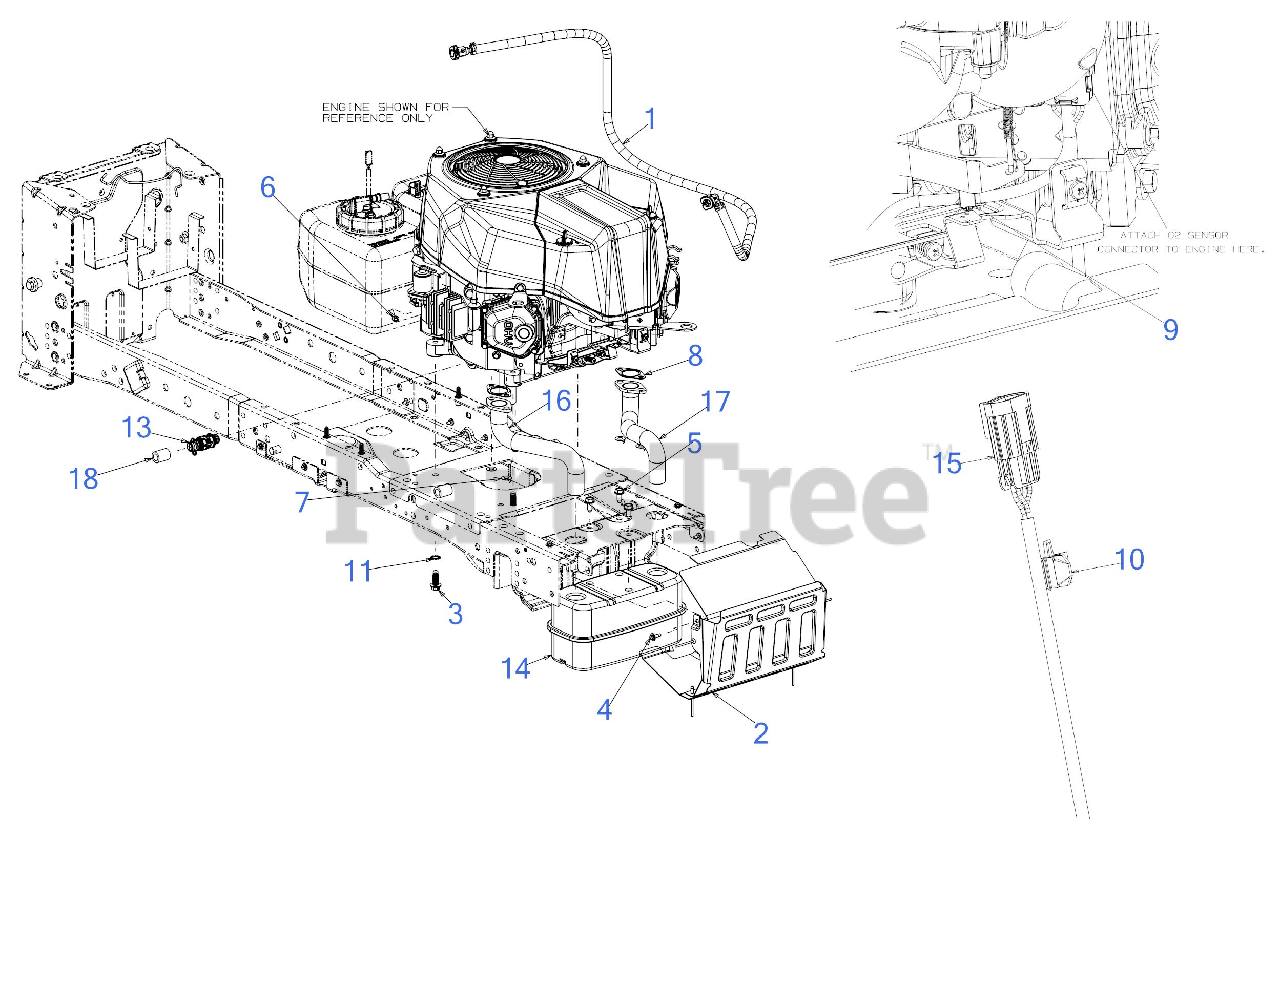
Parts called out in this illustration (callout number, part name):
1	HP FUEL HOSE ASSEMBLY
2	MUFFLER SHIELD ASSEMBLY
2	RIVET - 3/16"
3	SCREW 3/8-16 x 1
4	SCREW M6-1 x .625
5	SCREW M8-1.25 x .750
6	HEX NUT
7	HEX FLANGE NUT M8X
8	EXHAUST GASKET
9	WIRE CLIP
10	O2 SENSOR CLIP
11	LOCK WASHER 3/8
13	OIL DRAIN VALVE
14	EXHAUST MUFFLER (TWIN)
15	OXYGEN SENSOR ASSEMBLY
16	EXHAUST PIPE (RH)
17	EXHAUST PIPE (LH)
18	DRAIN HOSE 14''
